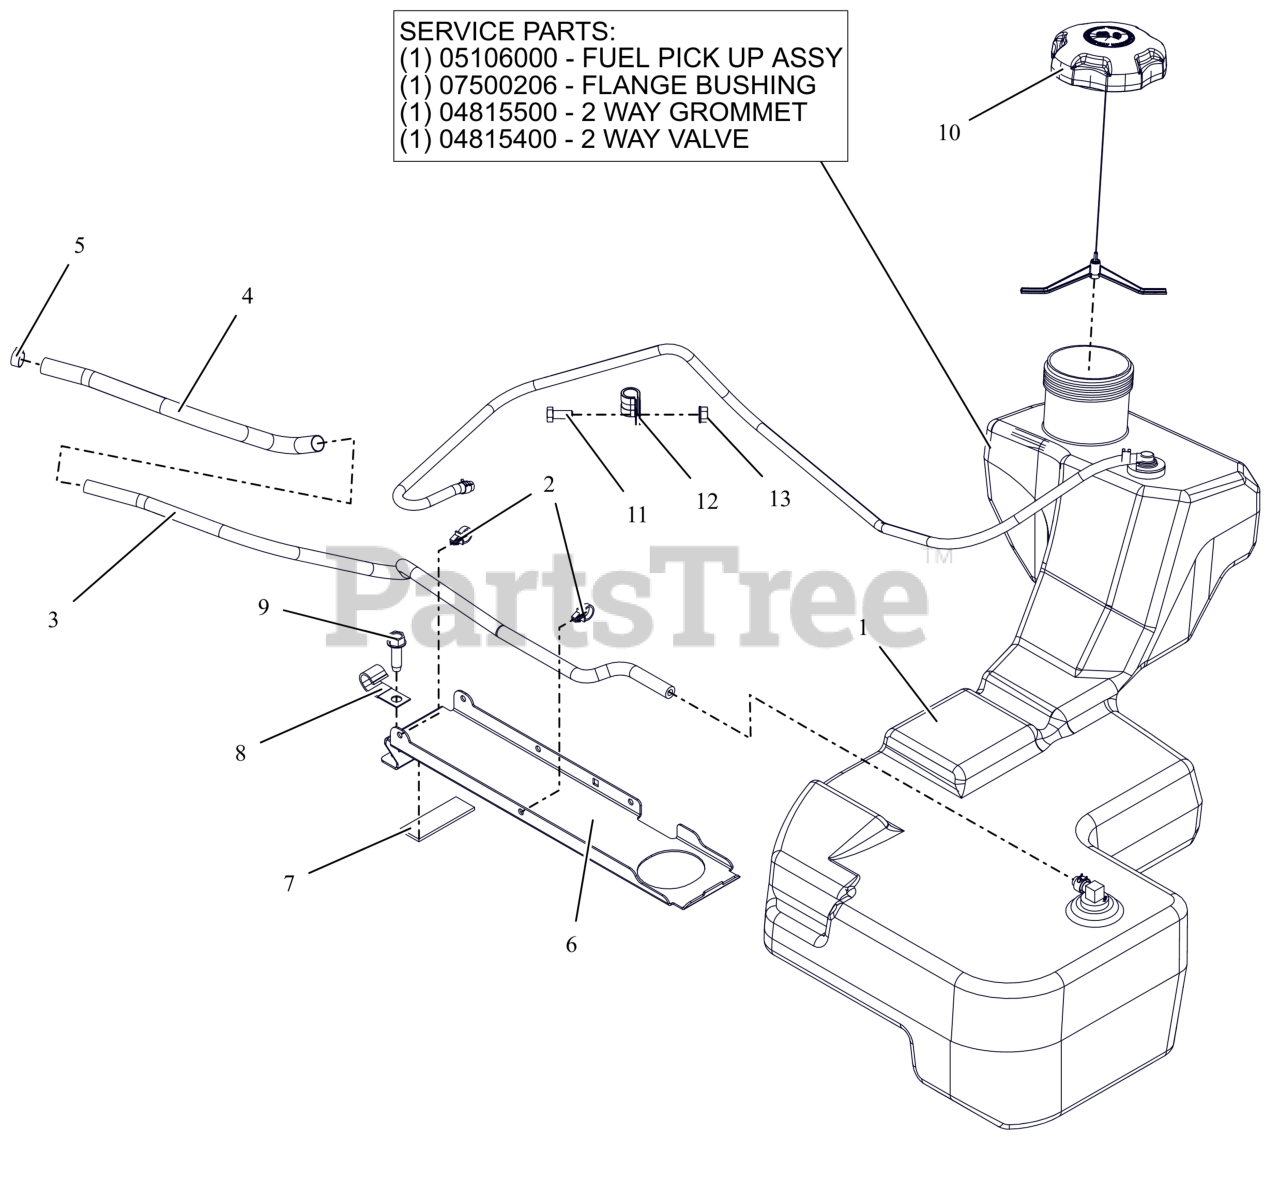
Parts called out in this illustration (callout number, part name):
1	ASM, FUEL TANK-HD
1	ASM, HD FUEL PICK-UP
1	BSHG-FLG .375X1.062X.625 NITR
1	GROMMET, 2-WAY
1	VALVE, 2-WAY
2	ROUTING CLIP (1/2" ID)
3	HOSE, .25 LOW-PERM BULK GAS
4	SLEEVE, THERMAL 12"
5	CLAMP, FUEL LINE
6	BRKT, FUEL TANK HOLD DOWN
7	PAD,RBR 1.0"X3.0" W/ADHESIVE
8	J-CLAMP
9	SCR,TAP .375-16X1.25HWH TR ZCC
10	CAP, FUEL - 3.50 RATCHET INLET VENT
11	BLT,HEX .31-18X.75 G5 ZCC
12	CLAMP, CUSHIONED STEEL
13	NUT,LK-CTR-FLG .31-18 GF ZCC
